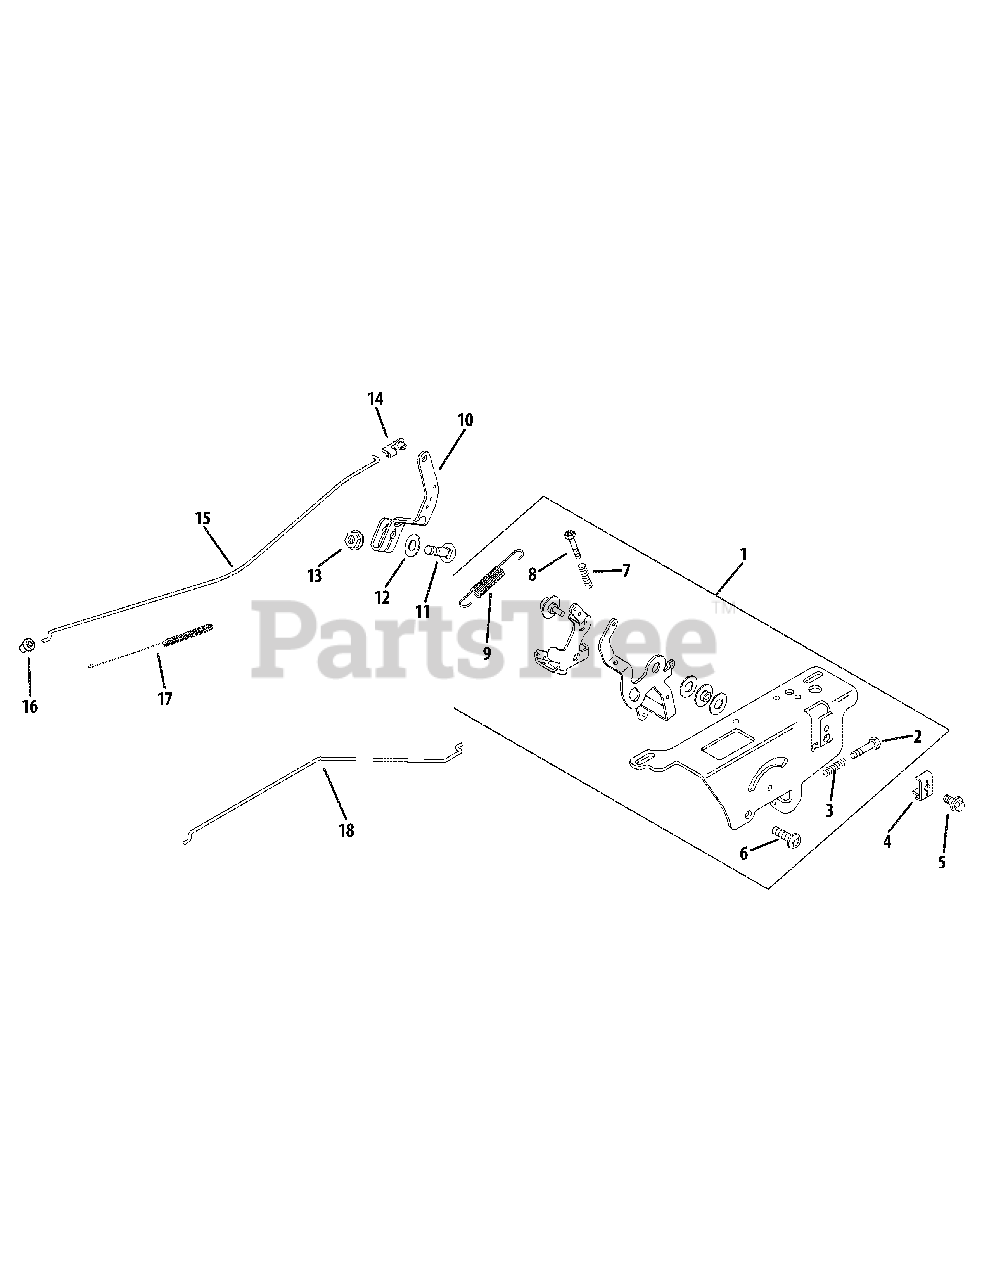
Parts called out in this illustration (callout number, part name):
1	Speed Cntrl. Ass. Kit
2	Phl Thd Frm Screw, M4 X 0.7 X 25
3	Speed Control Spring (Short)
4	Cable Clamp
5	Flg Thd Frm Screw, M5 X 0.8 X 16
6	Lbd Skt Screw, M6 x 1.0 x 20
7	Speed Control Spring (Short)
8	Phl Thd Frm Screw, M4 X 0.7 X 25
9	Governor Spring
10	Governor Lever
11	Rd Hd Sq Nck Bolt, 1/4-20 X 1"
12	Internal Tooth Lock Washer, 1/4"
13	Hex Flange Nut, 1/4-20"
14	Throttle Linkage Bushing
15	Throttle Linkage
16	Linkage Retaining Bushing
17	Linkage Spring
18	Choke Linkage
